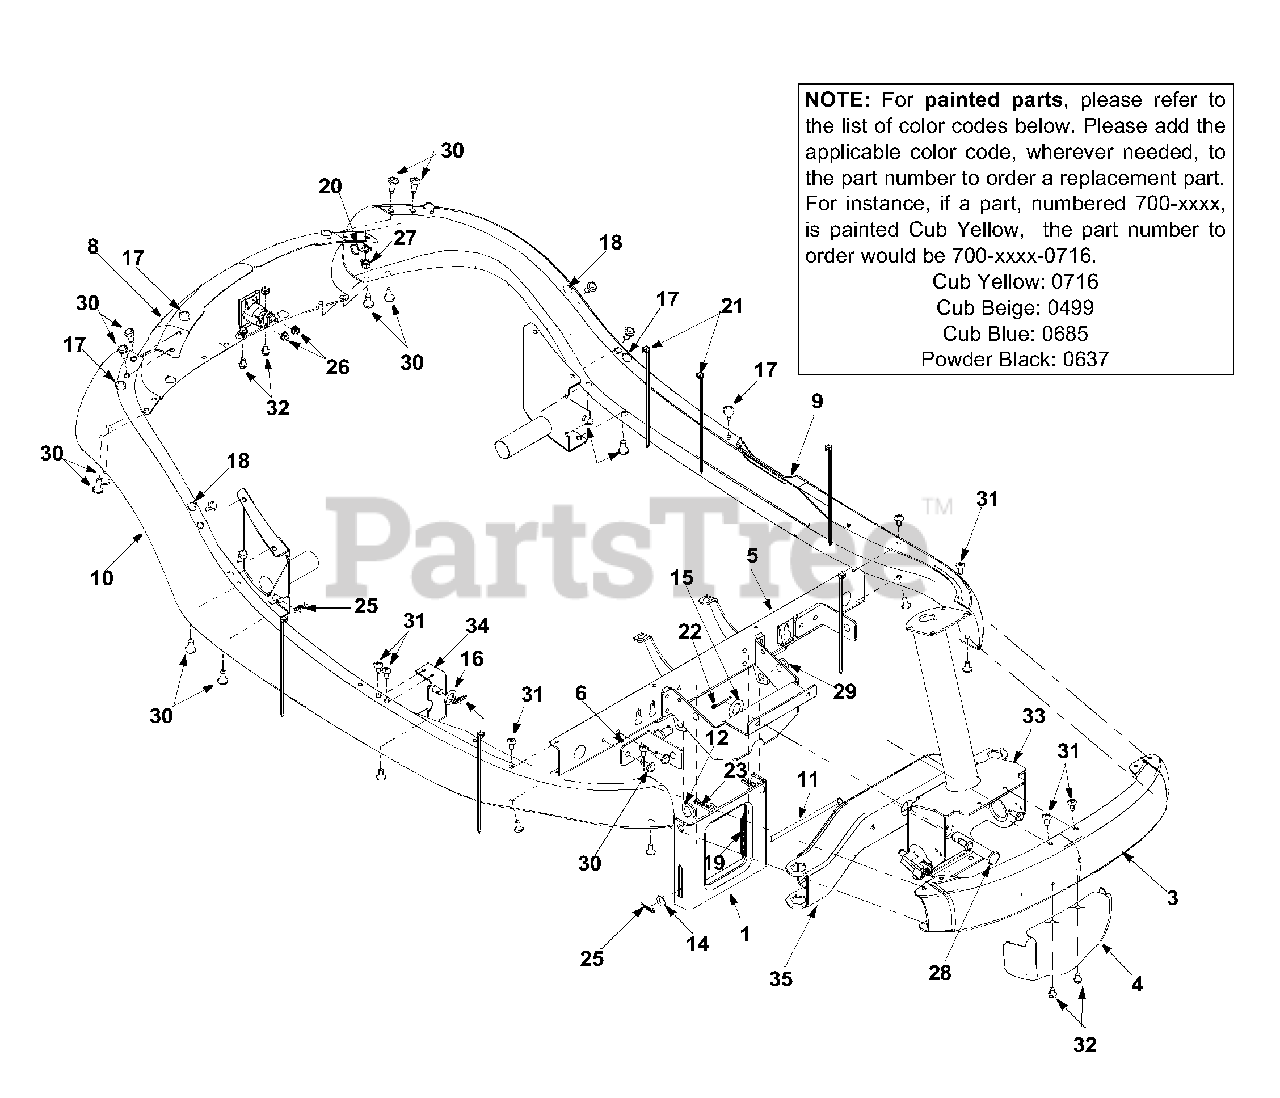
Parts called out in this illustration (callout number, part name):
12	Flat Washer .531 X 1.062 X .134
14	Flat Washer 5/16
15	Flat Washer .64 I.D. X 1.24 X .06
16	Flat Washer 3/8 X 1.00 X .030
17	Rubber Bumper
18	Rubber Bumper
19	Extension Spring
20	Clamp: 9/16 dia.
21	Cable Tie
22	Hairpin Clip
23	Hairpin Clip
25	Hairpin Clip
27	Hex Nut 1/4-20
28	Clevis Pin
29	Lift Bracket Pin
30	TT Screw 5/16-18 x .75
31	Torx Mach. AB Scr. 1/4-14 x 0.625"
32	Hex TT Screw 1/4-20
33	Steering Support Bracket
34	Pivot Bracket Assembly: Hood
